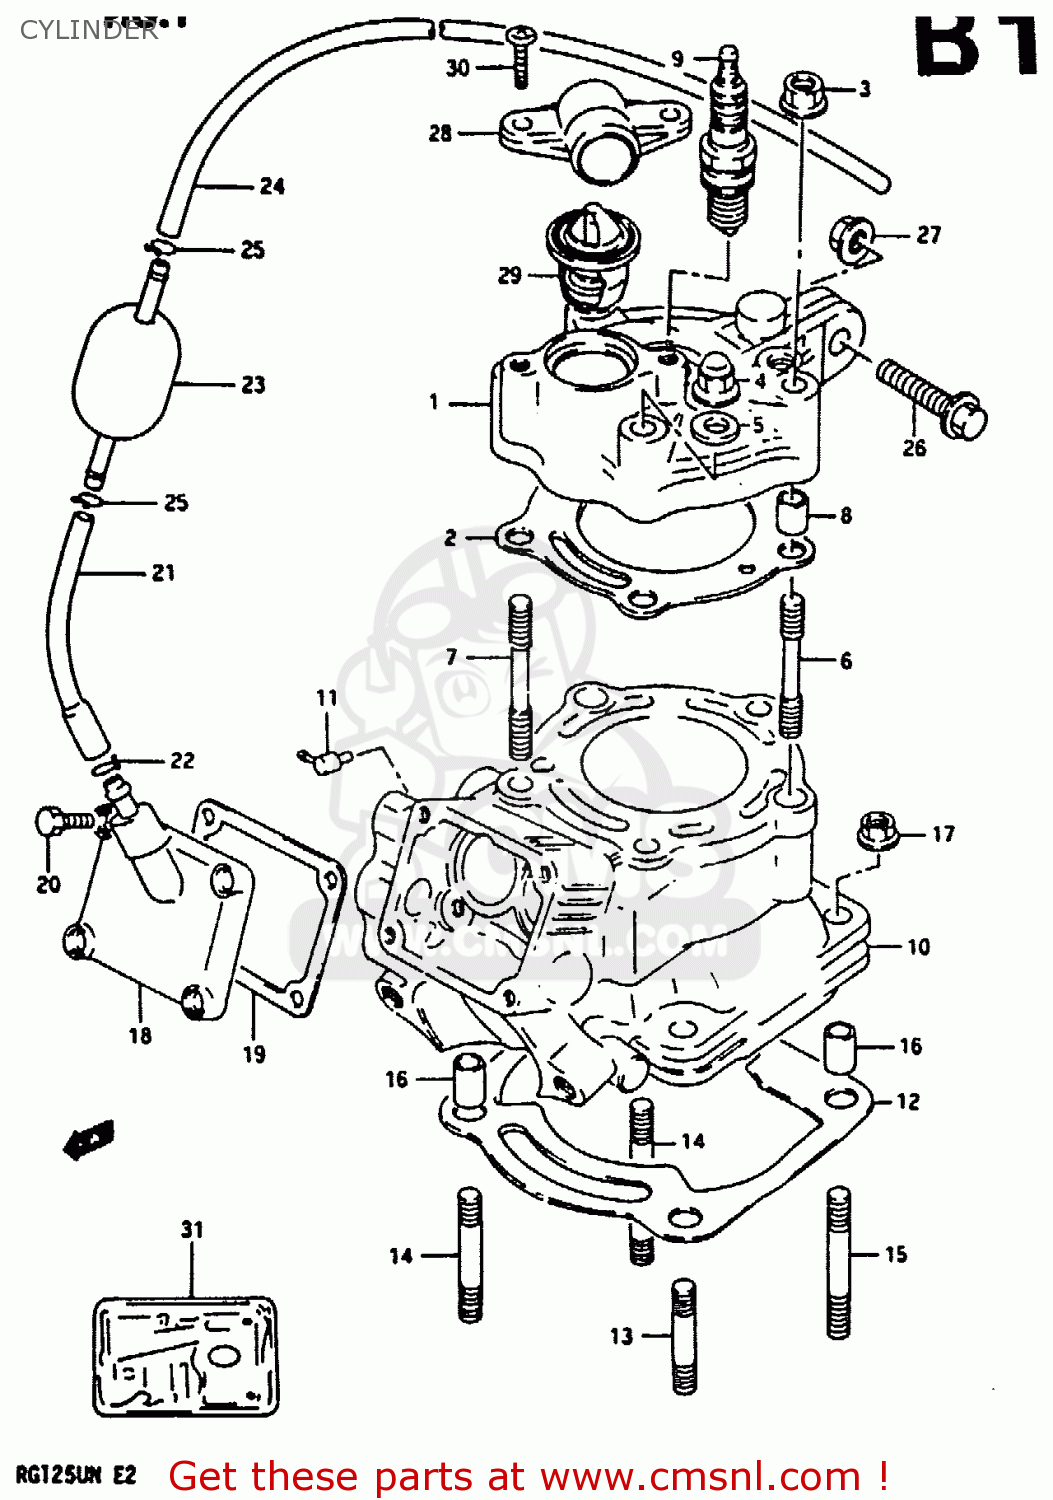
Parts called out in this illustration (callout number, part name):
1	HEAD, CYLINDER
2	GASKET,CYLINDER HEAD (NAS)
3	NUT
4	NUT
5	GASKET(8.5X17X2.3) (NAS)
6	STUD BOLT (L:45)
7	BOLT,HEAD STUD
8	PIN
9	PLUG,SPARK(BR9ECM)
10	CYLINDER
11	VALVE,OIL HOSE CHECK
12	GASKET, CYLINDER (NA)
13	BOLT,STUD
14	BOLT,STUD
15	BOLT,STUD
16	PIN
17	NUT
18	COVER, CYLINDER
19	GASKET,CYL COVER NO.2 (NAS)
20	BOLT
21	HOSE,FUEL
22	CLIP
23	VESSEL,SILENCER
24	HOSE
25	CLIP
26	BOLT 8X40
27	NUT
28	COVER,THERMOSTAT
29	THERMOSTAT COMP,WATER
30	SCREW
31	GASKET SET (NA)
